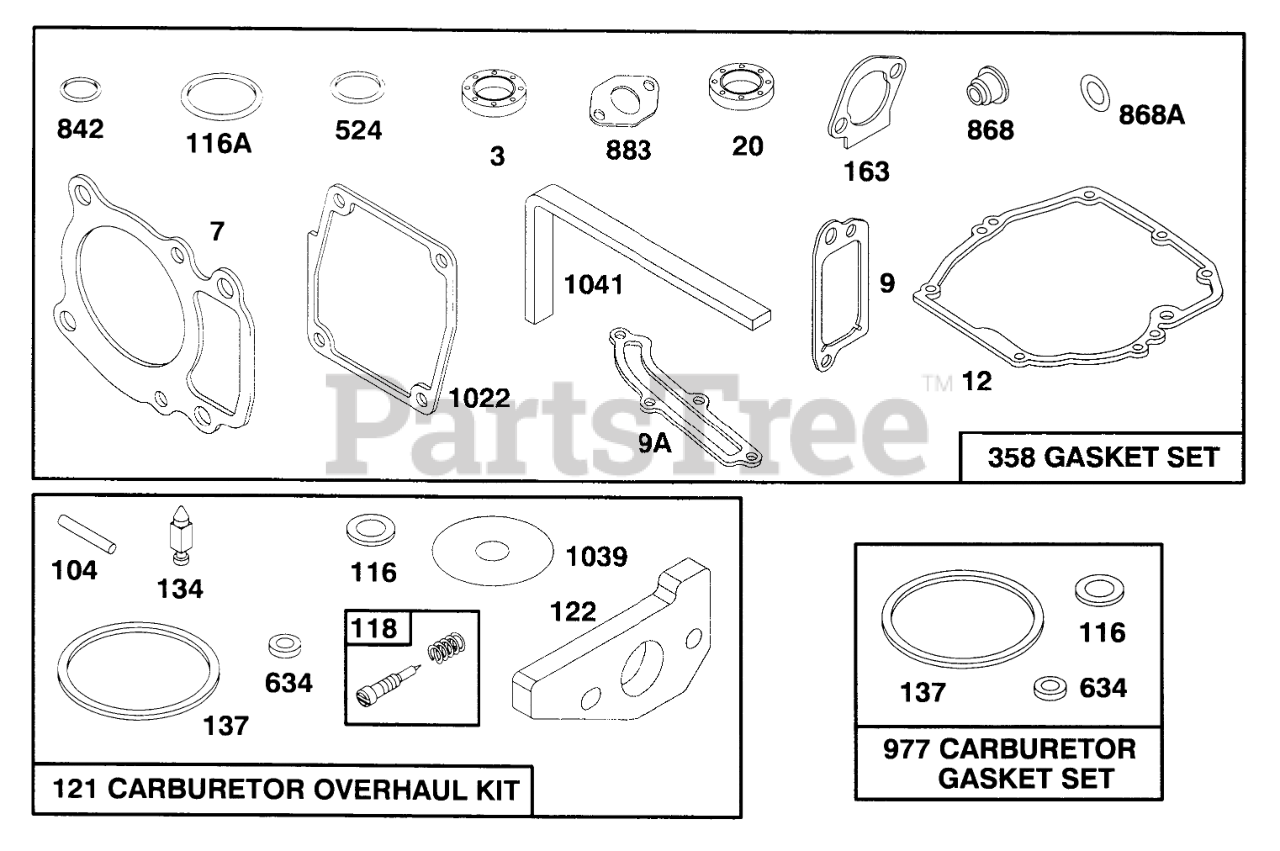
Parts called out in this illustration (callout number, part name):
3	SEAL - OIL
7	CYLINDER HEAD GASKET
9	BREATHER GASKET
9A	GASKET-BREATHER
12	ENGINE BASE GASKET
20	SEAL-OIL
104	FLOAT HINGE PIN
116	SEALING GASKET
116A	O RING SEAL
118	VALVE KIT - NEEDLE
121	CARBURATOR OVERHAUL KIT
122	ADAPTER ASSEMBLY
134	Valve-Inlet (Includes Seat)
137	FLOAT BOWL GASKET
163	AIR CLEANER GASKET
358	GASKET SET
524	O-RING
634	SEAL WASHER
842	O-RING
868	SealAssy-Valve
868A	Seal-Valve
883	EXHAUST GASKET
977	CARBURATOR GASKET SET
1022	ROCKER COVER GASKET
1039	VENT TUBE
1041	SEAL - FOAM
